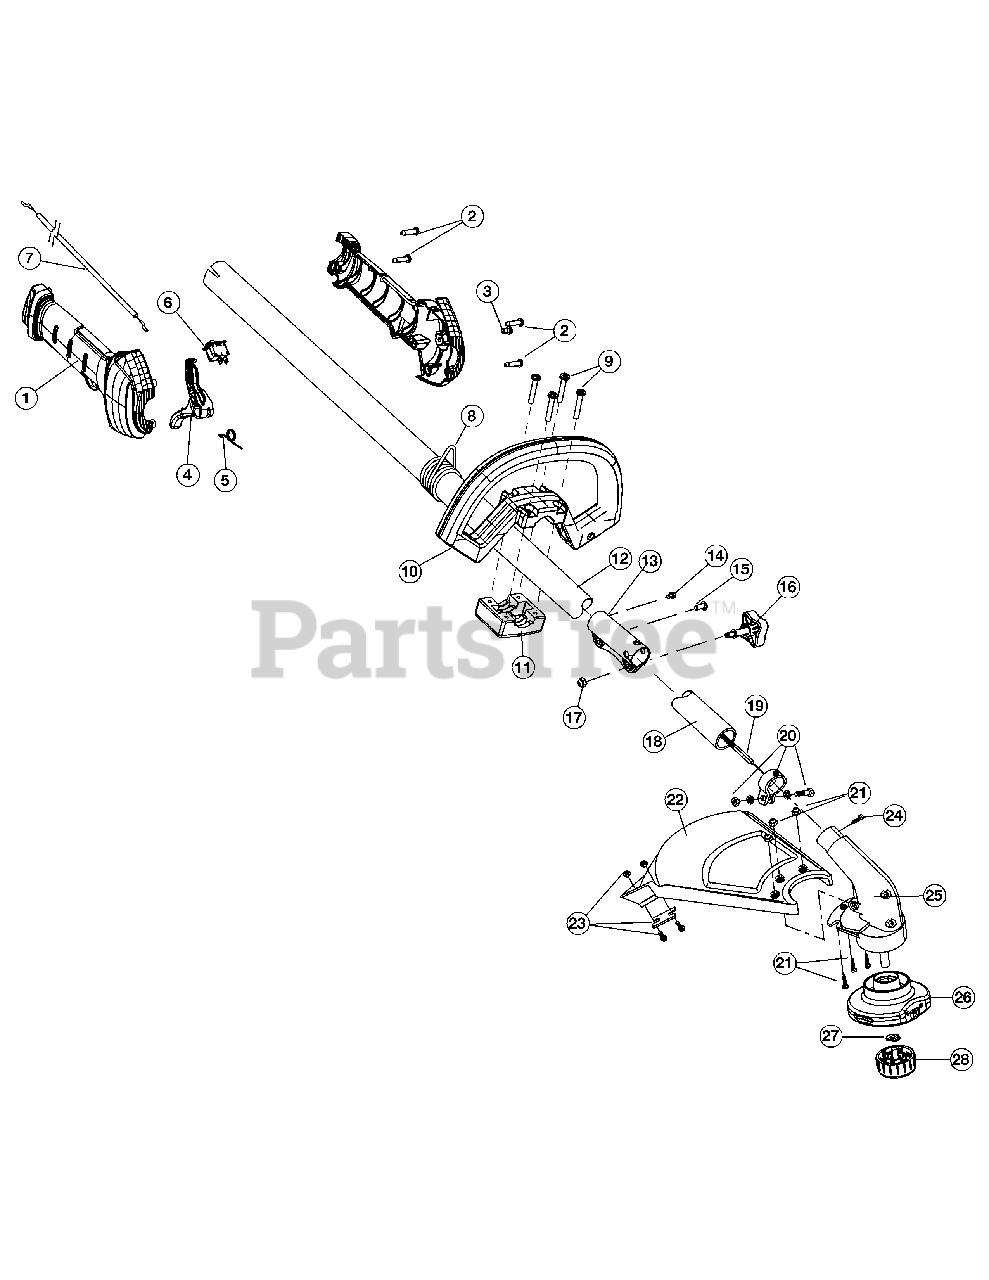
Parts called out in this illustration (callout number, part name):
1	Throttle Grip Assembly (includes 2-6)
2	Screw
3	Anti-Rotation Screw
4	Throttle Trigger
5	Throttle Trigger Spring
7	Throttle Cable
8	Harness Clip
11	D-Handle Base
12	Upper Drive Shaft Assembly
13	Split Boom Coupler Assembly (includes 14-17)
16	Knob (includes 17)
17	Nut
18	Lower Drive Shaft Housing Assembly
19	Lower Flex Shaft
20	Lower Clamp Assembly (includes 24)
21	Guard Mounting Screw Assembly
22	Gaurd Assembly (includes 23)
23	Blade Assembly
24	Anti-Rotation Screw
25	Gearbox Assembly (includes 20)
26	Fixed Head Line Assembly
27	Lock Washer
28	Bump Knob Assembly
